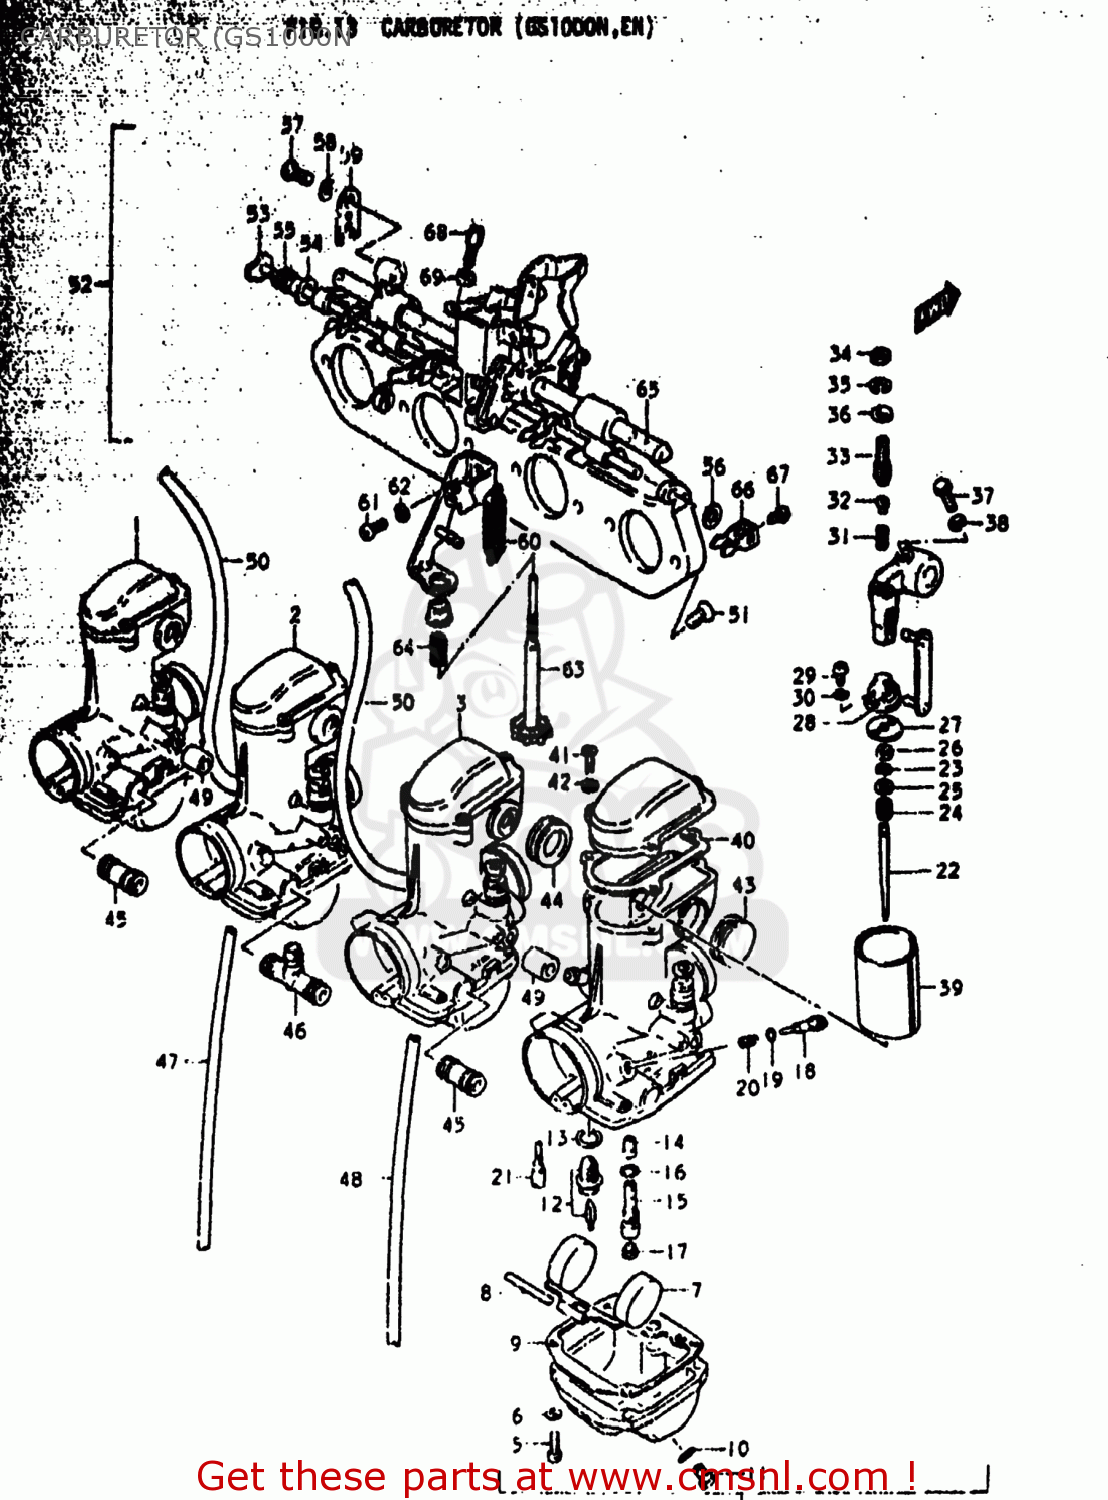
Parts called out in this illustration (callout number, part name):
1	CARBURETOR ASSEMBLY
2	CARBURETOR ASSEMBLY
3	CARBURETOR ASSEMBLY
4	CARBURETOR ASSEMBLY
5	SCREW
6	LOCK WASHER
7	FLOAT
8	PIN,FLOAT
9	GASKET,FLOAT CHAMBER (NAS)
10	O RING
11	SCREW
12	VALVE ASSEMBLY,NEEDLE
13	GASKET,VALVE SEAT (NAS)
14	JET,NEEDLE
15	PIPE,BLEEDER
16	O RING
17	JET,MAIN(95)
18	SCREW,PILOT AIR
19	O RING
20	SPRING
21	JET,PILOT
22	NEEDLE,JET
23	CLIP
24	SPRING
25	WASHER,JET NEEDLE
26	RING
27	PLATE,THROTTLE VALVE
28	CONNECTOR
29	SCREW
30	LOCK WASHER
31	SPRING
32	PIN,CARBURETOR
33	SCREW
34	NUT
35	LOCK WASHER
36	WASHER
37	BOLT
38	LOCK WASHER
39	VALVE,THROTTLE
40	GASKET (NAS)
41	SCREW
42	LOCK WASHER
43	PIPE,DELIVERY
44	SEAL
45	NIPPLE
46	NIPPLE
47	HOSE
48	HOSE
49	HOSE
50	HOSE 4.5X8X390
51	SCREW
52	CARBURETOR ASSEMBLY
53	SHAFT,STARTER
54	WASHER
55	SPRING
56	WASHER,STARTER SHAFT
57	SCREW
58	LOCK WASHER
59	GASKET
60	SPRING,THROTTLE RETURN
61	SCREW
62	LOCK WASHER
63	ADJUSTER
64	SPRING,THROTTLE SCREW
65	SHAFT ASSEMBLY
66	LEVER,STARTER
67	SCREW
68	ADJUSTER,CABLE
69	NUT
